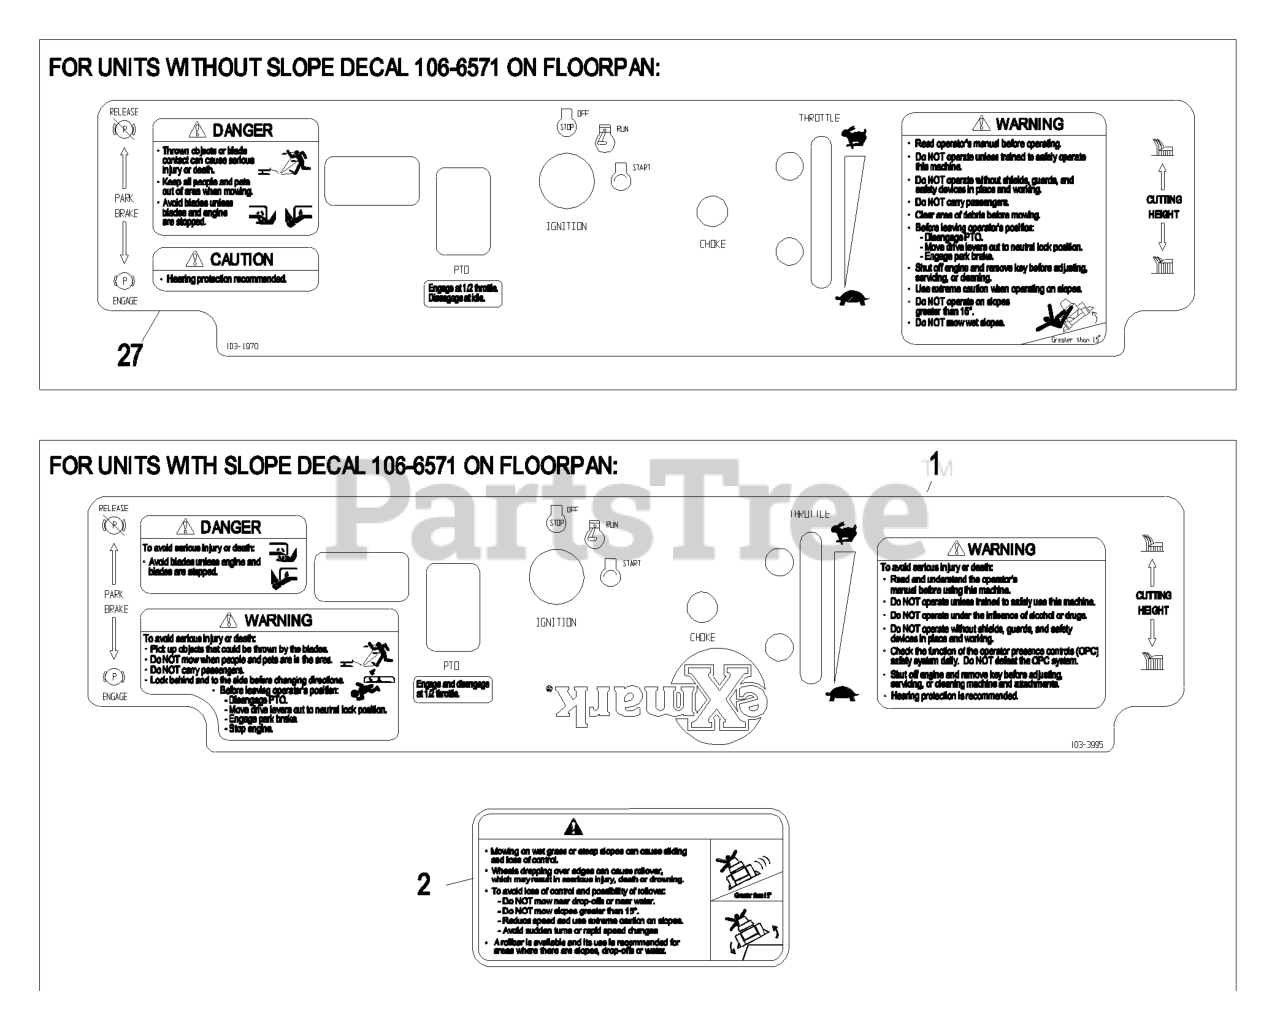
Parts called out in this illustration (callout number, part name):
1	DECAL,CONSOLE LHP
2	DECAL-DANGER, SLOPE
27	KIT,DECAL SLOPE LHP
